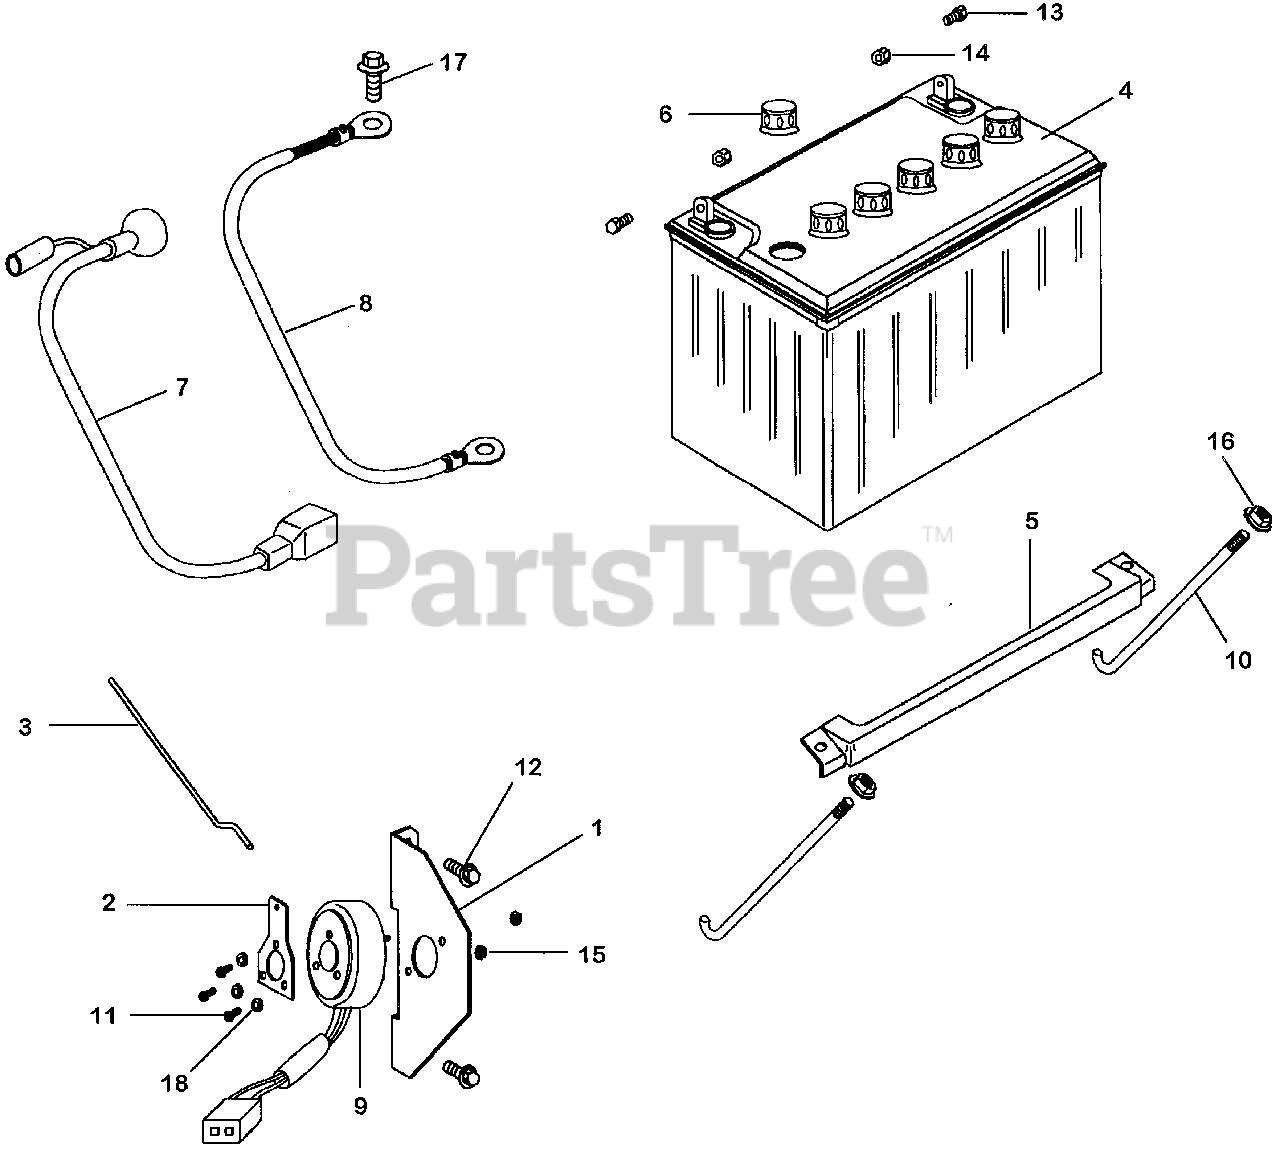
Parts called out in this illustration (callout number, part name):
1	PLATE, SOLENOID
2	ARM, SOLENOID
4	BATTERY ASSY. (34A19L-MF) (YUASA)
5	PLATE, BATTERY SETTING
6	PLUG, VENT (YUASA)
7	CABLE ASSY., STARTER
8	CABLE ASSY., GROUND
9	SOLENOID ASSY.
10	BOLT, BATTERY SETTING
11	SCREW (3.5X6)
12	BOLT, FLANGE (6X12) (CT200)
13	BOLT, BATTERY TERMINAL
14	NUT, BATTERY TERMINAL
15	NUT, FLANGE (4MM)
16	NUT, FLANGE (6MM)
17	BOLT, FLANGE (8X16) Use from Engine SN 1000016.
18	WASHER, PLAIN (4MM)
